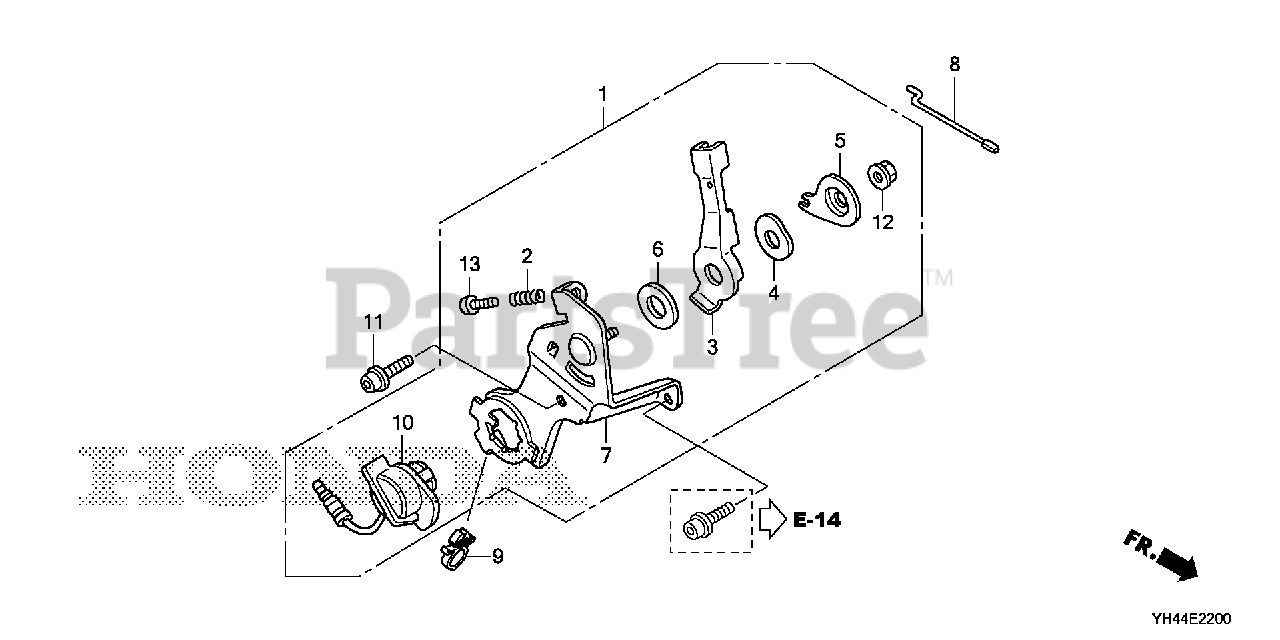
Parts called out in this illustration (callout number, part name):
1	CONTROL ASSY.
2	SPRING, CONTROL ADJUSTING
3	LEVER, CONTROL
4	SPRING, LEVER
5	WASHER, CONTROL LEVER
6	SPACER, CONTROL LEVER
7	BASE, CONTROL
8	ROD, THROTTLE
9	CLIP, IGNITION WIRE (8MM)
10	SWITCH ASSY., ENGINE STOP
10	SWITCH ASSY., ENGINE STOP (TOYO DENSO)
11	BOLT, SOCKET (5X10)
12	NUT, SELF-LOCK (6MM)
13	SCREW, PAN (5X25)
